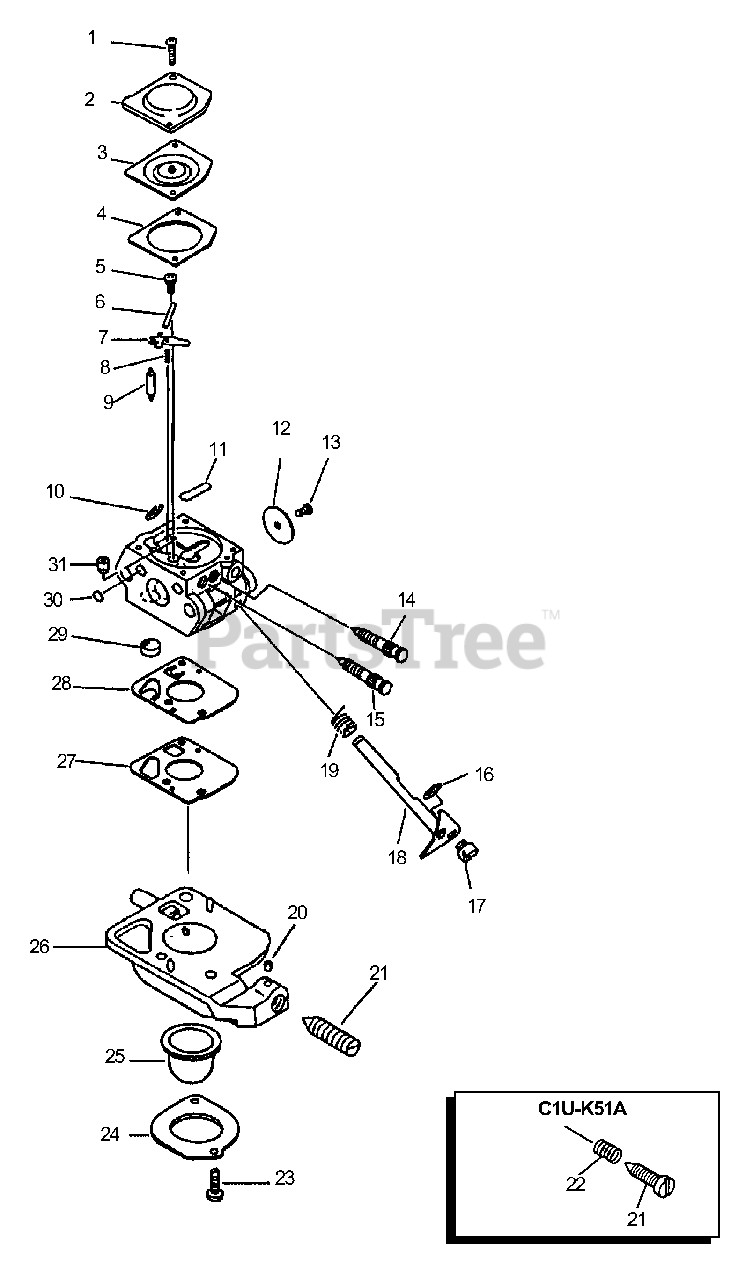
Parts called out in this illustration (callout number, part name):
2	COVER, METERING
3	DIAPHRAGM, METERING
4	GASKET, METERING
5	SCREW, METERING LEVER PIN
6	PIN, METERING LEVER
7	LEVER, METERING
8	SPRING, METERING LEVER
9	VALVE, NEEDLE
10	RING, RETAINING
11	PLUG, WELCH
12	VALVE, THROTTLE
14	NEEDLE - LOW SPEED
15	NEEDLE - HIGH SPEED
16	RING, RETAINING
18	SHAFT, THROTTLE
19	SPRING, RETURN
20	PIECE, FRICTION
21	SCREW, IDLE ADJUST
22	SPRING, IDLE ADJUST
23	SCREW, RETAINER
24	RETAINER, PURGE BULB
25	BULB, PURGE
26	BASE, PURGE
27	GASKET, PURGE
28	DIAPHRAGM, PURGE
29	STRAINER
30	PLUG, WELCH
31	NOZZLE, CHECK VALVE
